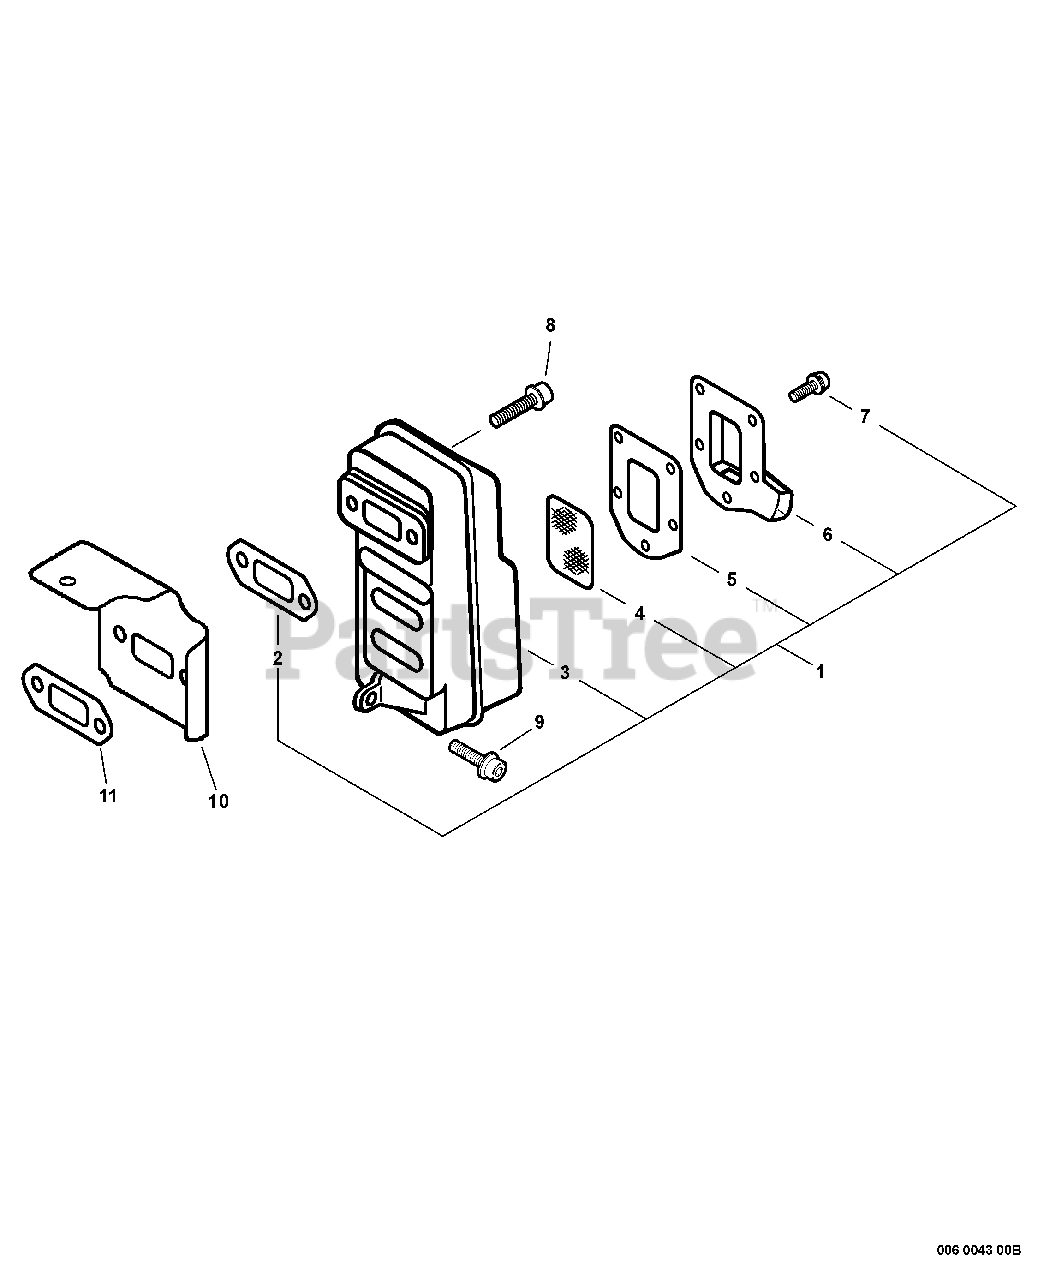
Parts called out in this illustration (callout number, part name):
1	MUFFLER ASSY
2	GASKET, EXHAUST
3	MUFFLER
4	SCREEN, SPARK ARRESTER
5	GASKET, EXHAUST
6	GUIDE, EXHAUST
7	SCREW 4×10
8	BOLT 6×20
9	BOLT 5×20
10	COVER, ENGINE - EXHAUST
11	GASKET, EXHAUST
